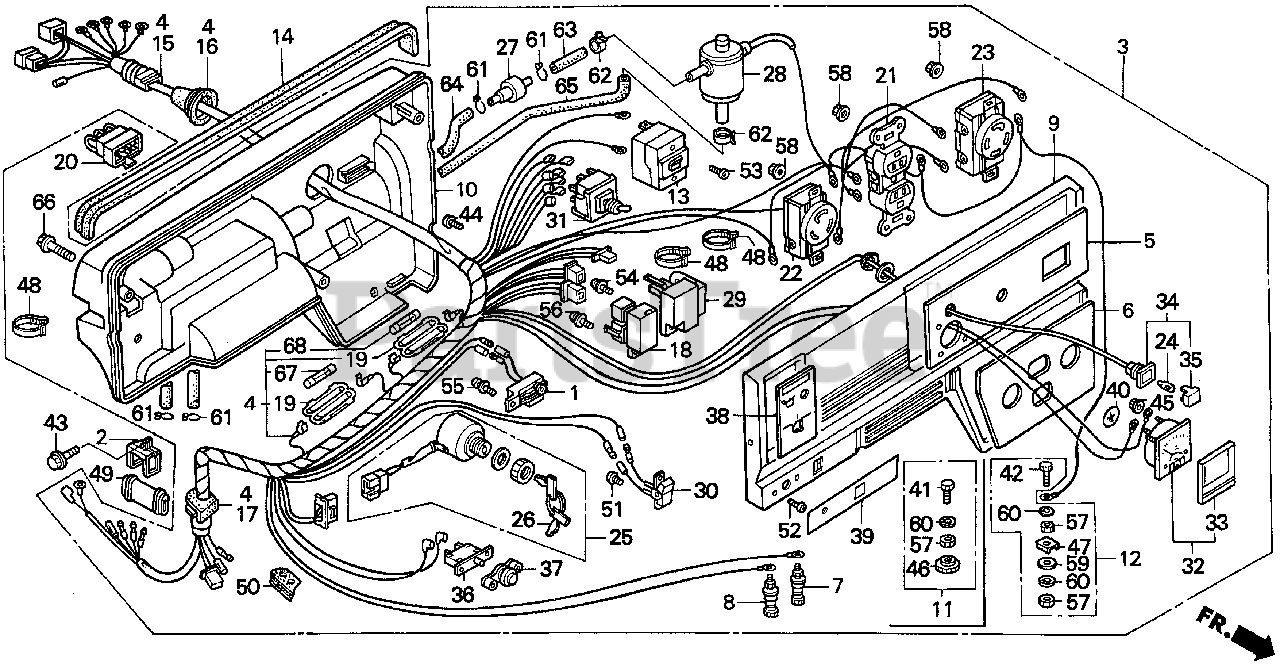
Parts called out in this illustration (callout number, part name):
1	ALERT UNIT, OIL (NOT AVAILABLE)
2	CLIP, WIRE
3	BOX ASSY., CONTROL *R8* (BRIGHT RED)
4	WIRE HARNESS ASSY.
4	WIRE HARNESS ASSY. (NOT AVAILABLE)
5	MARK, SWITCH PANEL (EMS-A)
6	MARK, A.C. OUT (NOT AVAILABLE)
7	TERMINAL, D.C. OUT (+)
8	TERMINAL, D.C. OUTPUT (-)
9	PANEL, CONTROL *R280* (POWER RED)
10	CASE, CONTROL *R280* (POWER RED)
11	TERMINAL SET, GROUND
12	TERMINAL SET, GROUND
13	BREAKER, CIRCUIT (13A)
14	RUBBER, CONTROL
15	GROMMET, A.C. WIRE
16	GROMMET, MAIN WIRE
17	GROMMET, SWITCH WIRE
18	DIODE ASSY.
19	CASE, FUSE CONNECTOR (SUMITOMO)
20	CONNECTOR ASSY.
21	RECEPTACLE (20A/125V) (MATSUSHITA)
22	RECEPTACLE (3-PRONG) (30A/125V)
23	RECEPTACLE (20A-125/250V) (MATSUSHITA) (NOT AVAILABLE)
24	BULB, WEDGE BASE (12V/2W) Use from Frame SN 1001725.
25	SWITCH ASSY., COMBINATION
26	KEY
27	VALVE, DASHPOT CHECK
28	VALVE ASSY., SOLENOID
29	THROTTLE UNIT, AUTO (SAWAFUJI)
30	SWITCH, AUTO THROTTLE
31	SWITCH ASSY., VOLT CHANGE
32	METER ASSY., VOLT (300V)
33	LENS, METER
34	SOCKET ASSY., LAMP (GREEN) Use from Frame SN 1001725.
35	LENS (GREEN) Use from Frame SN 1001725.
36	PROTECTOR, CIRCUIT (D.C.)
37	LENS ASSY., PROTECTOR
38	MARK, ENGINE SWITCH (EMS-A)
39	MARK, D.C. OUT (NOT AVAILABLE)
40	MARK, GROUND
41	BOLT, HEX. (6X22)
42	BOLT, HEX. (6X28)
43	BOLT, FLANGE (6X12) (CT200)
44	SCREW, GLOVE BOX
45	NUT, FLANGE (3MM) Use from Frame SN 1001725.
46	NUT, SPECIAL (6MM)
47	RETAINER (6MM)
48	TIE, CABLE (NATURAL 225X5.0)
49	TUBE, CORD
50	GROMMET, TUBE
51	SCREW, PAN (3X6)
52	SCREW, PAN (3X12)
53	SCREW, PAN (4X6)
54	SCREW-WASHER (5X12)
55	SCREW-WASHER (4X10)
56	SCREW-WASHER (4X12) Use up to Engine SN 2056819.
57	NUT, HEX. (6MM)
58	NUT, FLANGE (4MM)
59	WASHER, PLAIN (6MM)
60	WASHER, SPRING (6MM)
61	CLIP, TUBE (B7)
62	CLIP, TUBE (D8)
63	BULK HOSE, VACUUM (3.5X8000) (3.5X130)
64	BULK HOSE, VACUUM (3.5X8000) (3.5X130)
65	BULK HOSE, VACUUM (3.5X8000) (3.5X130)
66	BOLT, FLANGE (6X40)
67	FUSE B (5A)
68	FUSE B (10A)
